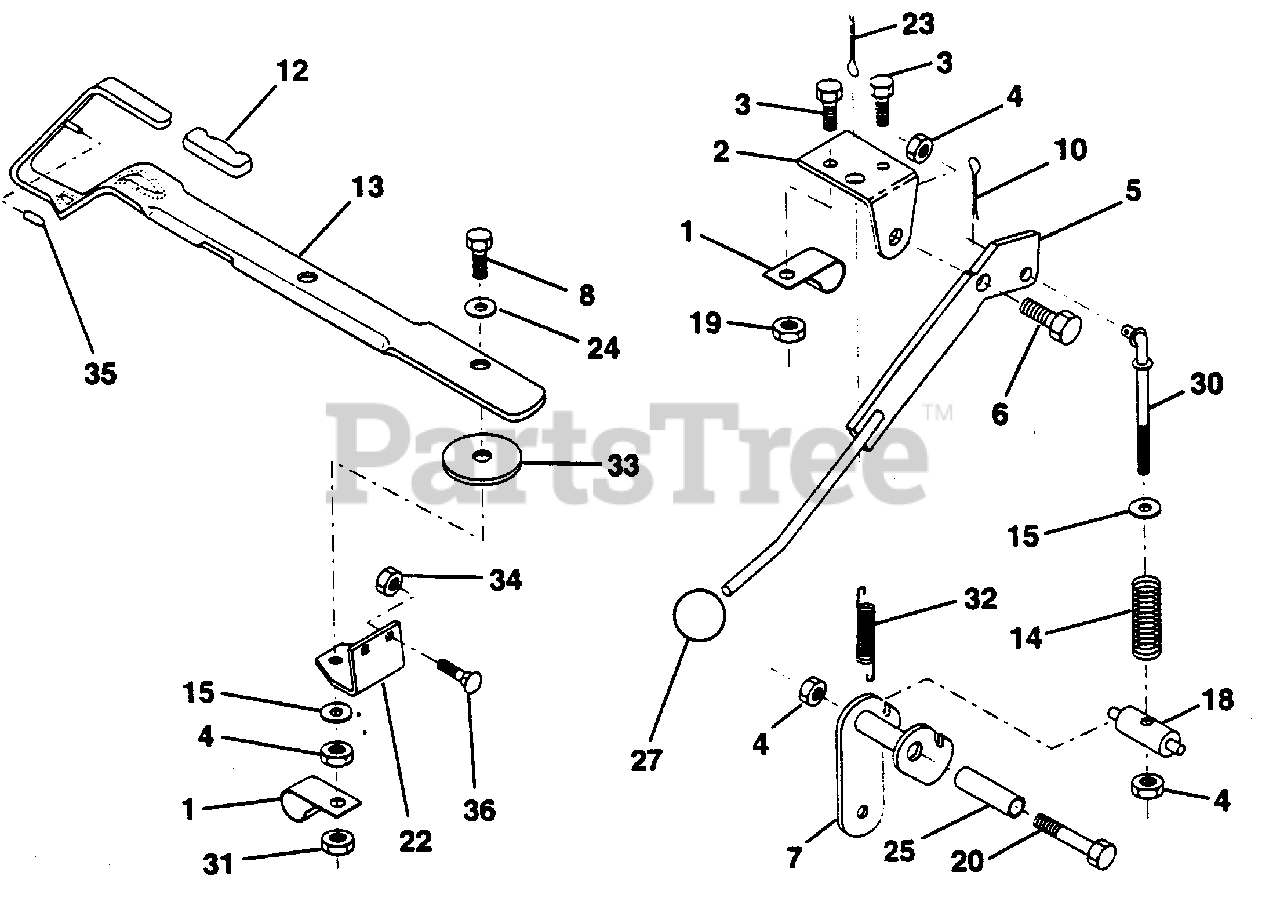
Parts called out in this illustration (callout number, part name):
1	Clip, Insulated (AYP part number)
2	Bracket, Mower Clutch (AYP part number)
3	Bolt, Hex Head, Fin. 1/4-20 UNC x 1/2 Grade 5 (AYP part number)
4	Nut,Lock Hex w/Wsh 3/8-16 (AYP part number)
5	Assembly, Clutch Lever (AYP part number)
6	Bolt, Shoulder (AYP part number)
7	Assembly, Mower Clutch Arm (AYP part number)
8	Bolt, Hex Head 3/8-16 UNC x 1-1/2 (AYP part number)
10	Pin, Cotter 1/8 x 3/4 (AYP part number)
12	Handle, Lift Lever (AYP part number)
13	Assembly, Lift Handle (AYP part number)
14	Spring, Compression (AYP part number)
15	Washer 13/32 x 1 x 11 Gauge (AYP part number)
18	Trunnion, Threaded 3/8-16 (AYP part number)
19	Nut, Crownlock 1/4-20 (AYP part number)
20	Bolt, Hex Head, Fin. 3/8-16 UNC x 2-3/4 (AYP part number)
22	Bracket, Lift Lever (AYP part number)
23	Pin, Cotter 3/32 x 3/4 (AYP part number)
24	Washer 25/64 x 1-1/4 x 12 Gauge (AYP part number)
25	Tube, Spacer (AYP part number)
27	Knob (AYP part number)
30	Rod, Tension, Clutch (AYP part number)
31	Nut, Centerlock (AYP part number)
32	Spring, Extension, Return (AYP part number)
33	Washer .390 x 1.437 x .074 (AYP part number)
34	Nut,Lock Hex w/Ins 5/16-18 (AYP part number)
35	Cap, Vinyl, Red (AYP part number)
36	Bolt, Carriage 5/16-18 x 3/4
